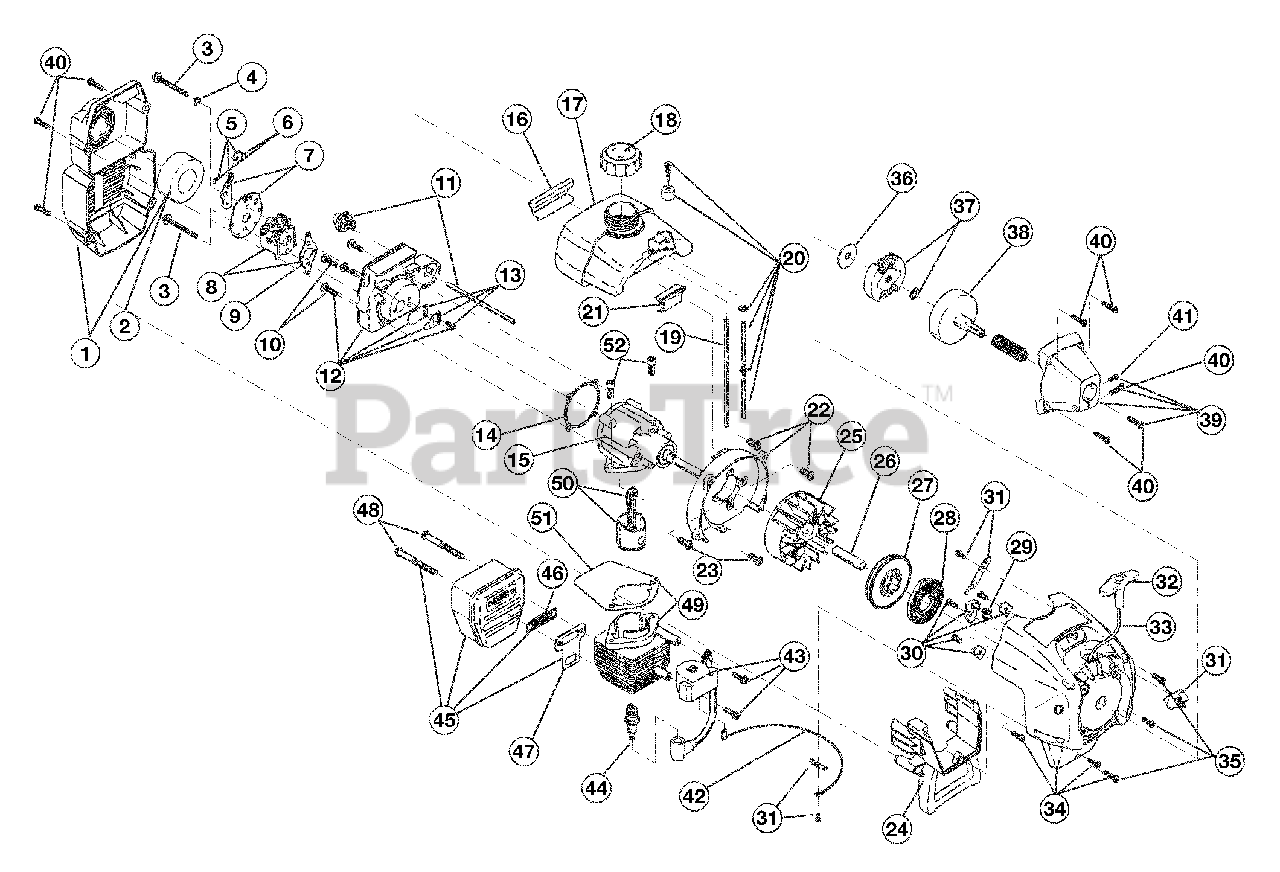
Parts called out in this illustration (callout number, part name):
1	Air Cleaner/Muffler Cover Assembly
2	Air Cleaner Filter
3	Carburetor Mounting Screw Assembly
4	Wavey Washer
5	Choke Lever Assembly
6	Choke Knob and Screw
7	Choke Lever and Plate
8	Carburetor Assembly
9	Carburetor Gasket
10	Carb Mount Screw
11	Primer and Hose Assembly
12	Carb Mount Assembly
13	Reed Assembly
14	Carburetor Mount Gasket
15	Crank Case Service Assembly
16	Rear Mounting Pad
17	Fuel Tank Assembly
18	Fuel Cap Assembly
19	Fuel Return Line
20	Fuel Line Assembly
21	Front Mounting Pad
22	Shroud Assembly
23	Shroud Screw
24	Shroud Extension & Stand
25	Flywheel Assembly
27	Recoil Pulley Assembly
28	Recoil Spring
29	Rope Guide
30	Pulley Retainer Assembly
31	Switch Assembly
32	Pull Handle
34	Starter Housing Assembly
35	Housing Screw
36	Clutch Washer
37	Clutch Rotor Assembly
38	Clutch Drum Assembly
39	Clutch Cover Assembly
41	Anti-Rotation Screw
42	Wire Lead
43	Module Assembly
44	Spark Plug
45	Muffler Assembly
46	Spark Arrestor Screen
47	Exhaust Gasket
48	Muffler Mounting Bolt
49	Cylinder Assembly
50	Piston and Rod Assembly
51	Cylinder Gasket
52	Cylinder Bolt
